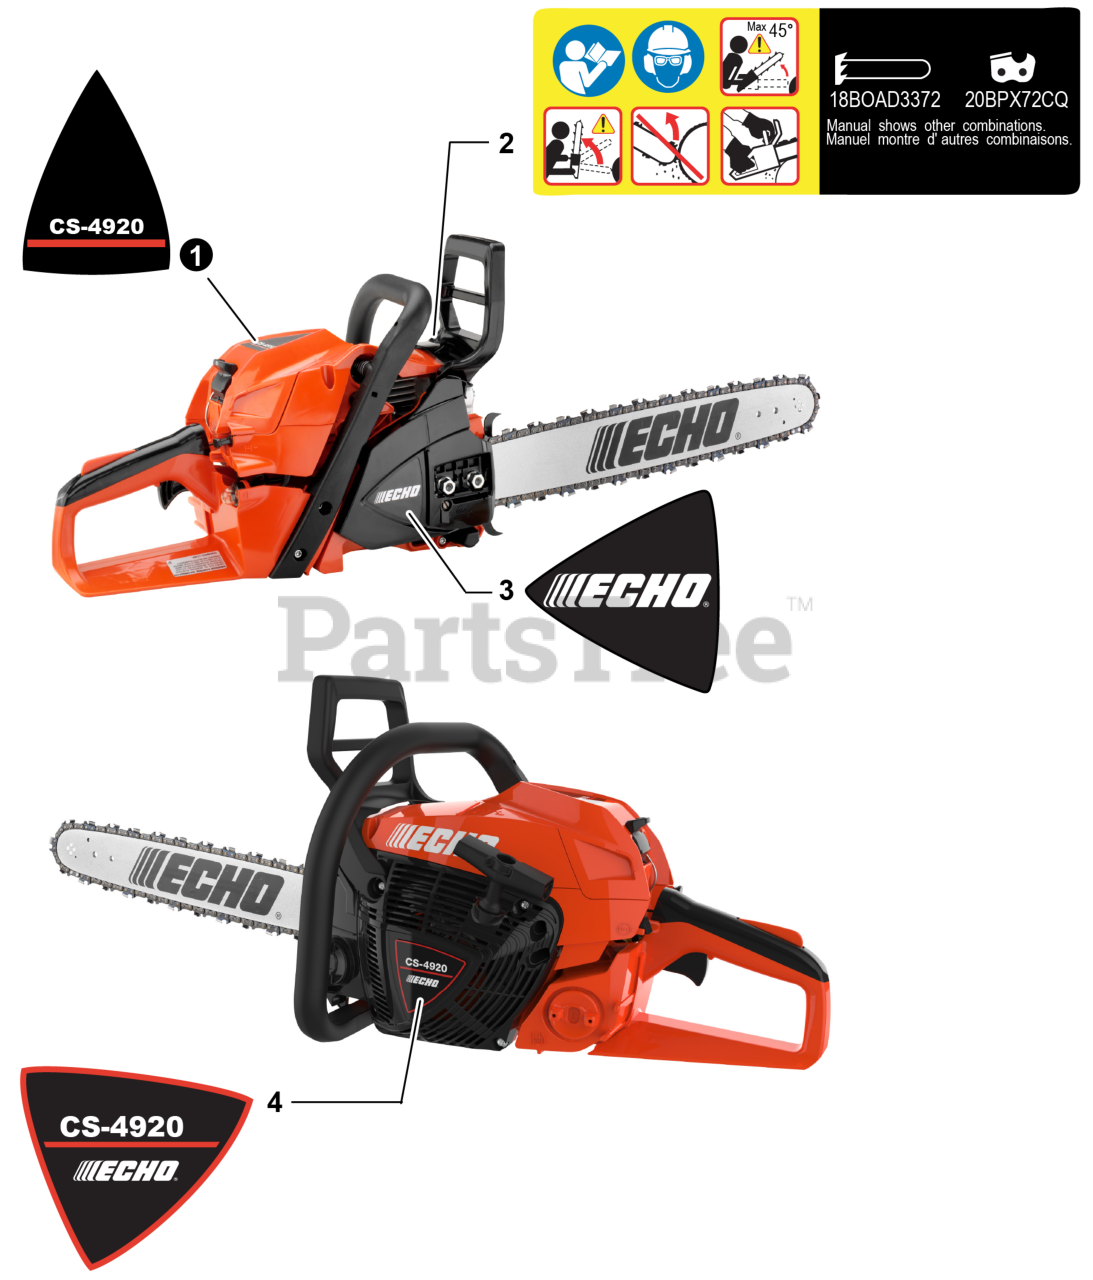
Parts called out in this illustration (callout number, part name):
1	LABEL - MODEL CS-4920
2	LABEL - CAUTION
3	LABEL - ECHO
4	LABEL - RECOIL STARTER - CS-4920
